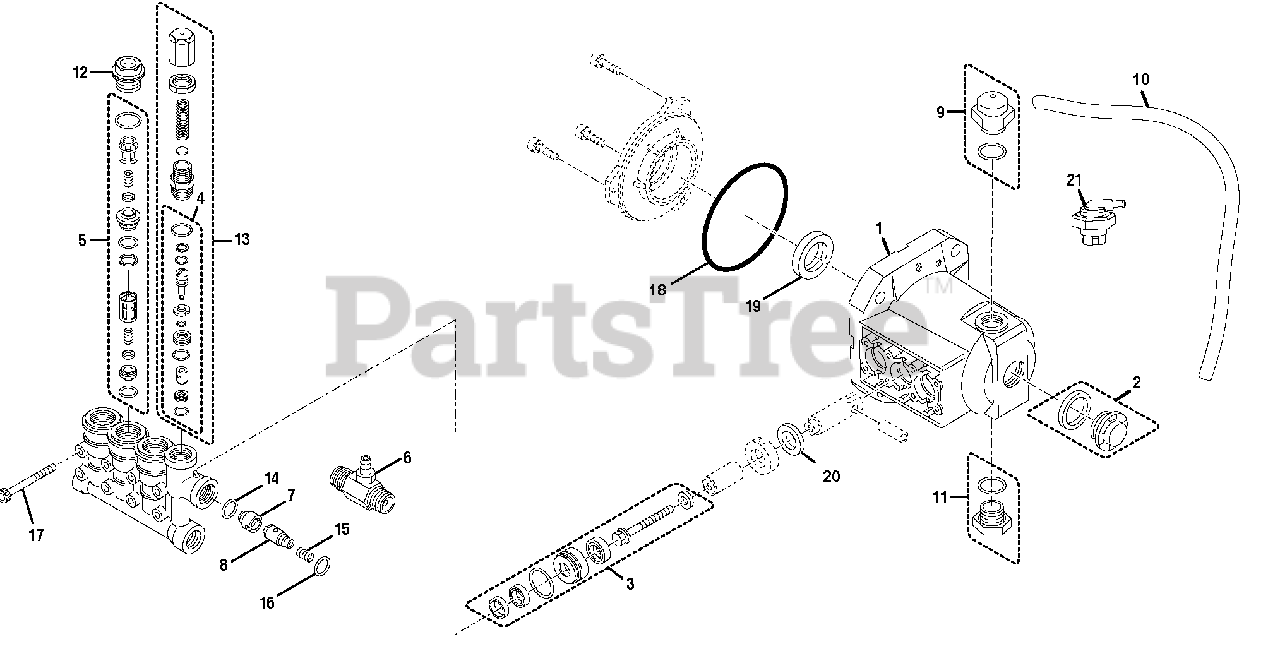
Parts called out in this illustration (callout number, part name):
1	Pump Assembly (Inc. Key Nos. 2-9 and 11-20)
2	Bubble Oil Gauge w/Gasket
3	Seal Kit
4	O-Ring Kit
5	Valve Kit (Set of 3)
6	Chemical Injector
7	Check Valve Seat
8	Check Valve w/O-Ring
9	Vent Cap (CAT)
10	Tube (Optional, 11 in.)
11	Drain Plug
13	Unloader Assembly (Inc. Key No. 4)
17	Bolt (M6)
19	Oil Seal
20	Oil Seal
21	Vent Cap (Optional)
